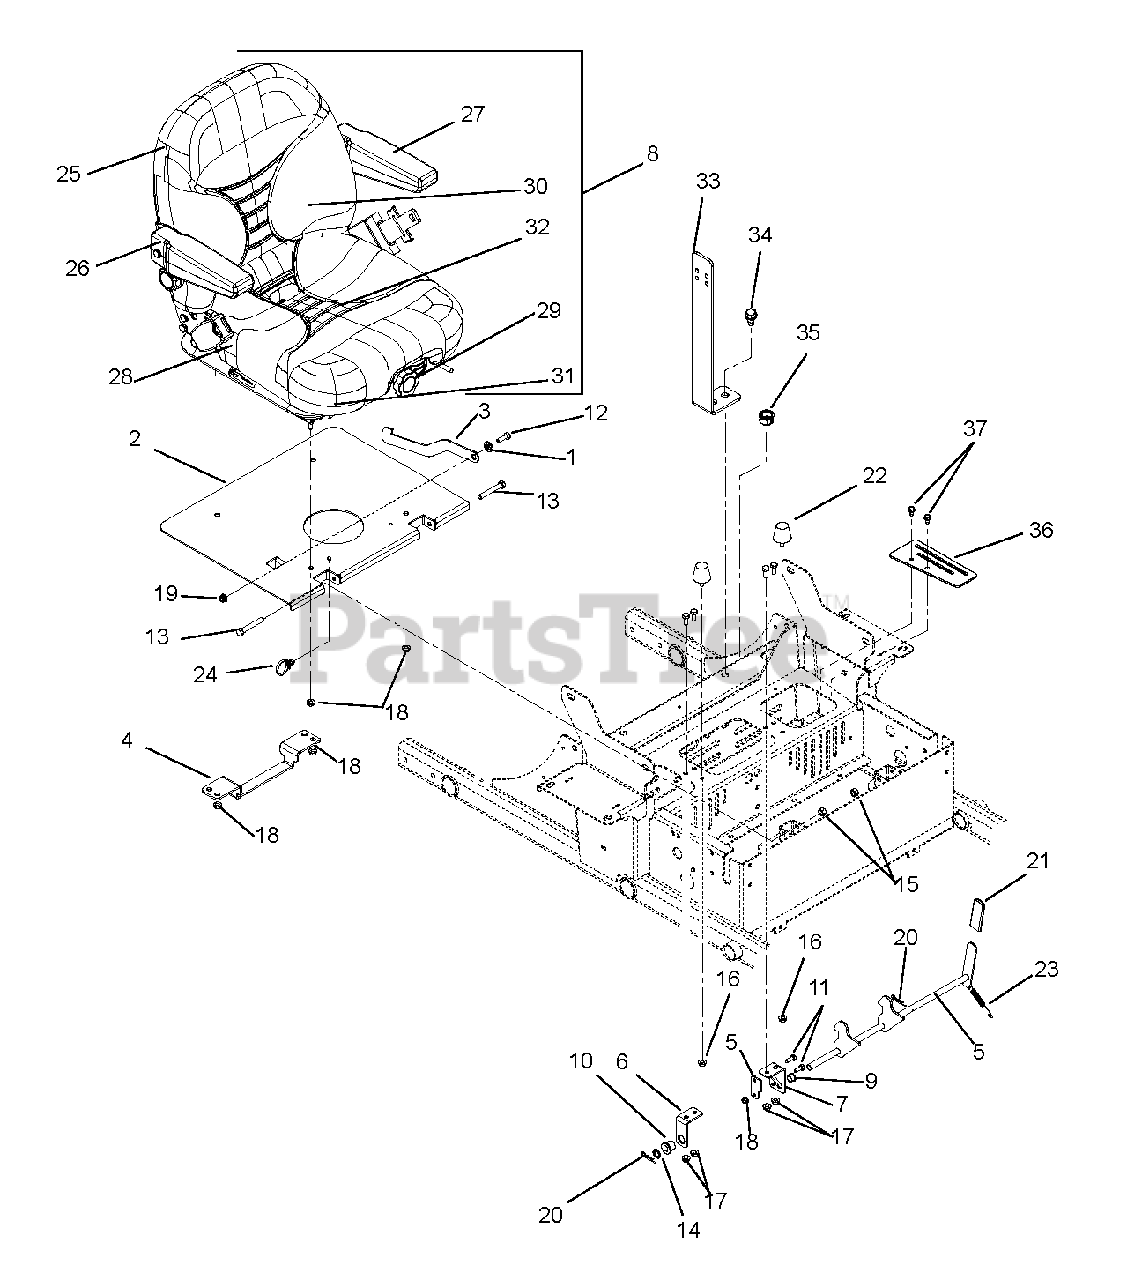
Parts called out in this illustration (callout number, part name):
1	Bushing, Flange .325 x .499 x .26 x .88
2	Seat Plate Weldment – Black
3	Stop, Seat Pivot
4	Bracket, Seat Latch
5	Weldment, Seat Latch
6	Mount, Seat Latch – Right Hand
7	Mount, Seat Latch – Left Hand
8	Seat, SUSP, with Seat Belt, Light Gray
9	Bushing, Polyliner – .50 Split
10	Bushing, Flange .515 x .750 x .745 x 1.00NY
11	Bolt, Hex .25-20 x .75 GR5 YWZC
12	Bolt, Hex .31-18 x .75 GR5 YWZC
13	Bolt, Hex .38-16 x 2.50 GR5 YWZC
14	Washer, Flat Steel .52 x .827 x .062 YWZC
15	Nut, Locking Center .38-16 YWZC
16	Nut, Spin Lock Flange .312-18 YWZC
17	Nut, Locking Top Flange .31-18 YWZC
18	Nut, Locking Top Flange .25-20 YWZC
19	Nut, Locking Nylon Flange .31-18 YWZC
20	Pin, Hair Internal .08 x .38 x 1.42 YWZC
22	Bumper, Rubber Cone, Stud Mount
23	Spring, Tension .043 x .44 x 3.31 WLD 5.8
24	Cable Tie with Tree (.25 HOLE)
25	Kit, Back Cushion, Light Gray
26	Kit, Armrest Assembly – Right Side
27	Kit, Armrest Assembly – Left Side
28	Kit, Seat Cushion, Light Gray
29	Kit, Seat Knobs
30	Kit, Seat Back
31	Kit, Seat Slides
32	Kit, Seat, Spring and Saddle
33	Mount, Switch PT200 CE
34	Screw, Tapping .31-18 x .50 Hex Washer Head Thread Rolling (lubricated or waxed)
35	Bushing, Panel Snap .687 x .875 x .56
36	Guard, Seat Plate Finger
37	Screw, Tapping .25-20 x .50 Hex Washer Head Thread Rolling
